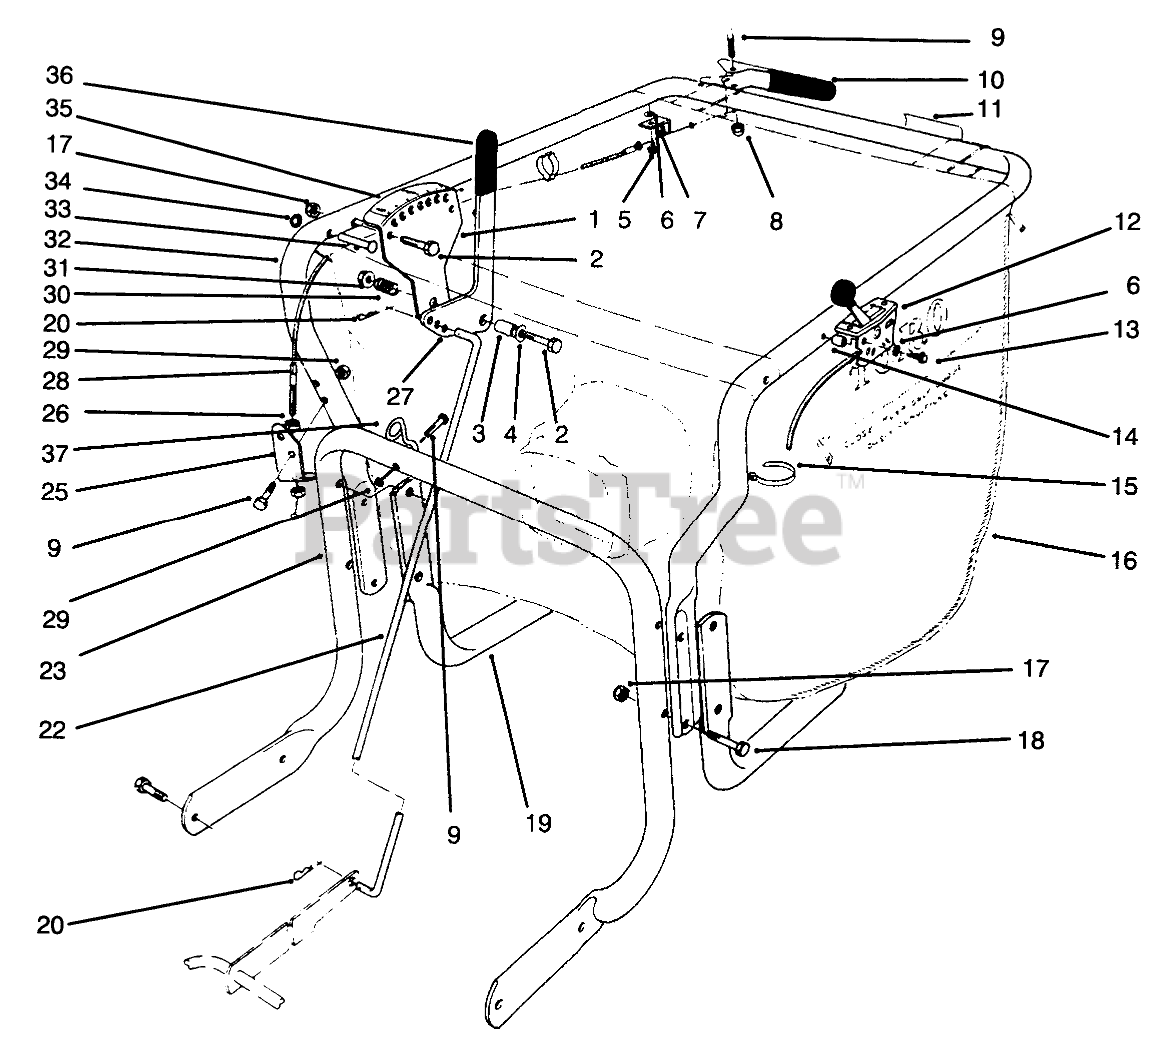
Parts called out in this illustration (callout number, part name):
1	Adjustment Bracket
2	SCREW-HH
3	SPACER
4	WASHER-FLAT
5	SCREW-HWH
6	WASHER-LOCK, EXT
7	RETAINING-CLIP
8	NUT-CAP
9	SCREW-HH
10	LEVER
11	DECAL-CONTROL, TRACTION
12	THROTTLE CONTROL
13	10-24 X 1 PAN HD SCR
14	SPACER
15	TIE-CABLE
16	VACUUM BAG
17	NUT-LOCK, NI
18	SCREW-HH
19	Support-Bag
20	PIN-COTTER
22	HEIGHT ADJ. ROD
23	HANDLE
25	MOUNT-BOWDEN, LOWER
26	NUT-KEPS
27	Handle-Adjustment
28	ASM - FORWARD CABLE
29	NUT-LOCK, NI
30	SPRING-COMPRESSION
31	NUT-HF
32	HANDLE-UPPER, VACUUM
33	RIVET
34	NUT-PUSH IN
35	DECAL-ADJUSTMENT, HEIGHT
36	GRIP-HANDLE
37	GUIDE-ROPE
